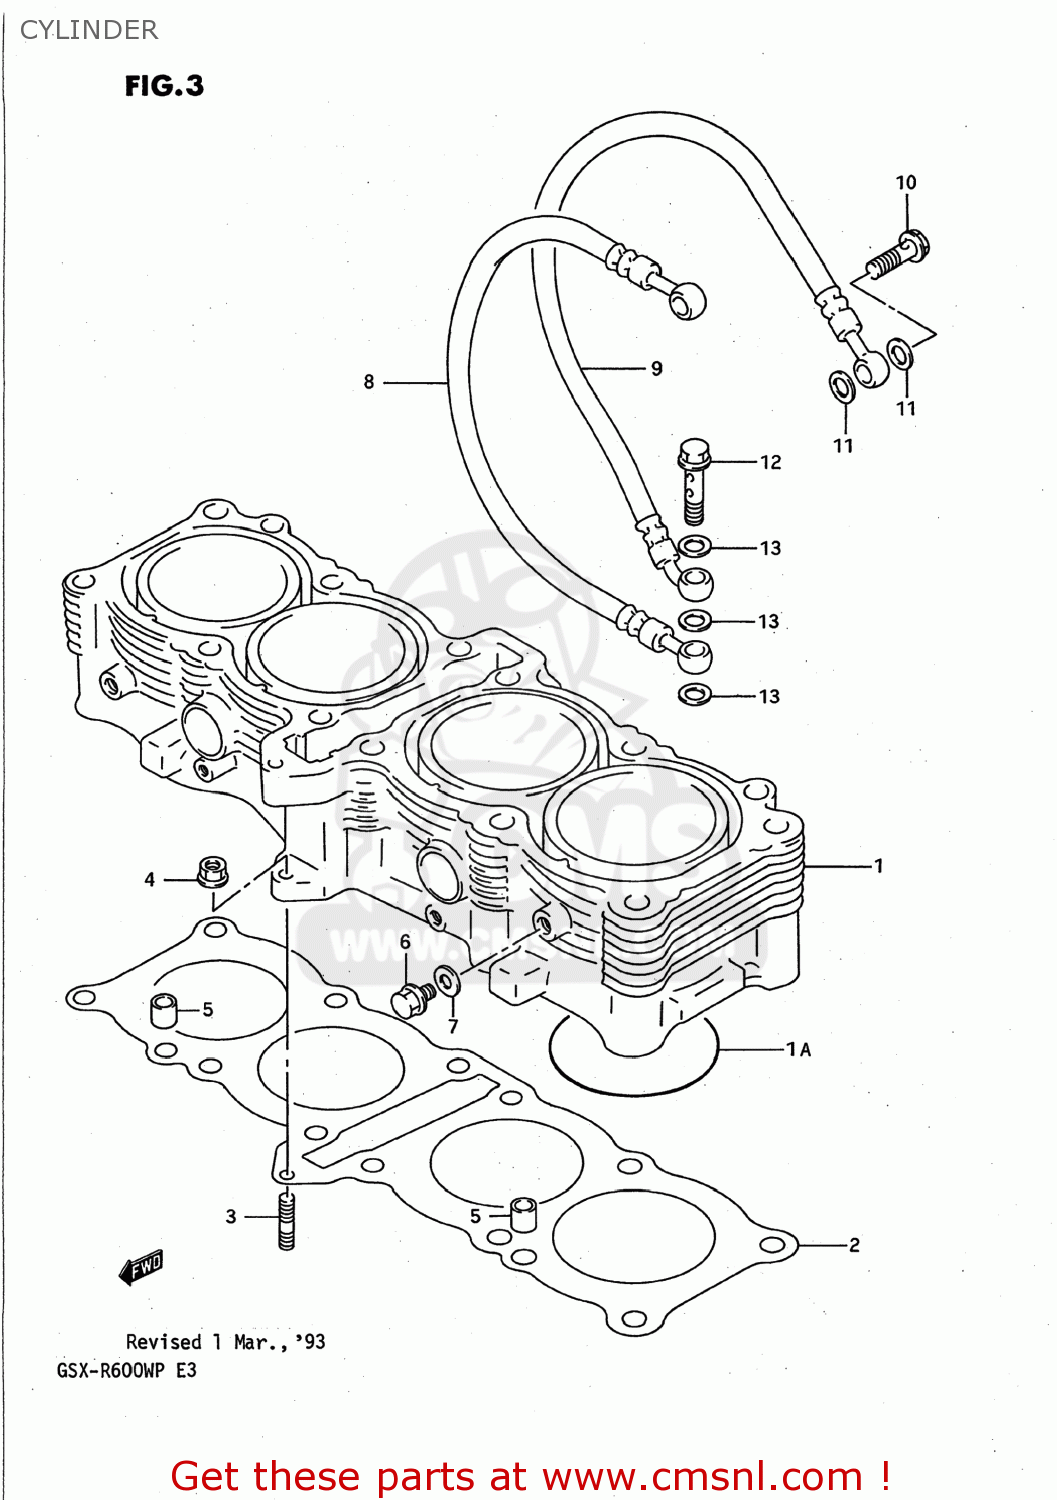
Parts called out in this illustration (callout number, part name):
1	CYLINDER
1A	O-RING
2	GASKET,CYLINDER
3	STUD BOLT L:20
4	NUT 6MM
5	PIN
6	BOLT,DRAIN
7	GASKET 8.2X14X1 (NAS)
8	HOSE,OIL
9	HOSE,OIL
10	BOLT,OIL PIPE UNION,NO
11	GASKET (NAS)
12	BOLT,OIL PIPE UNION,NO
13	WASHER(10X15X1.5)
